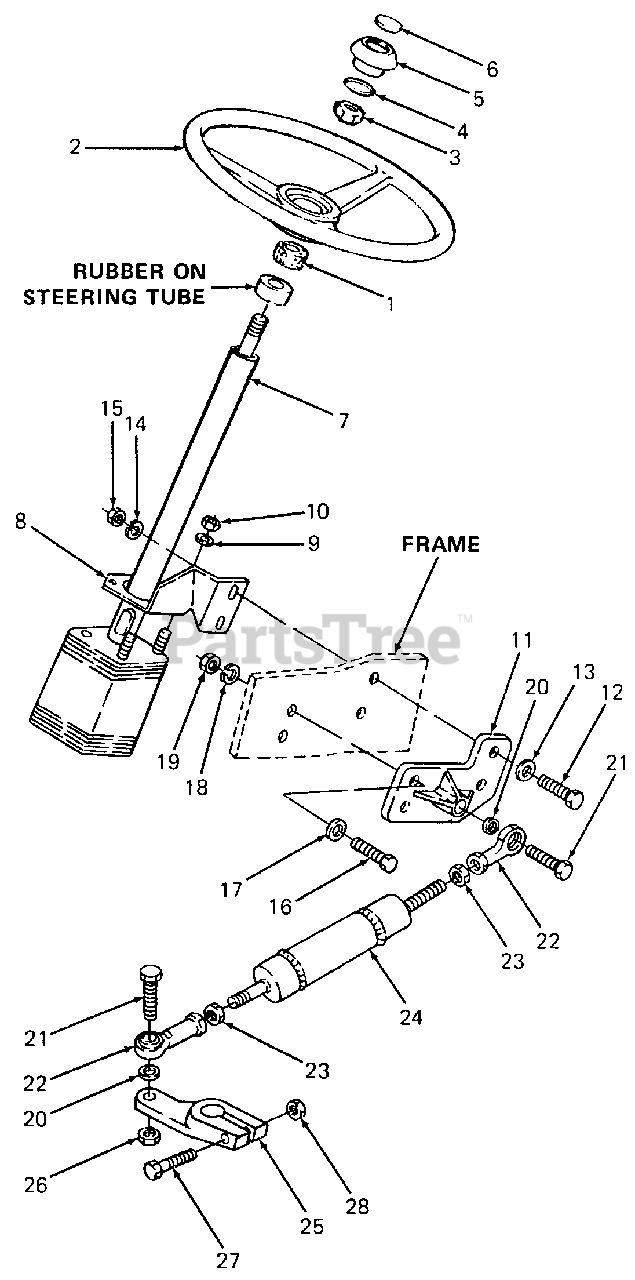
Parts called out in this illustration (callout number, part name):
1	Seal, Steering Gear
2	Wheel, Steering
3	Nut, Hex Jam, 5/8-18
5	Cap, Steering Wheel
6	Label, Steering Cap
7	Steering Column Assy
8	Bracket, Steering Mounting
9	Washer, Bell, .345 X .88 X .060 Thk
10	Nut, Hex, 5/16-24 GR5
13	Washer, Flat, .385 X .87 X .06 Thk HDN
14	Washer, Lock, 3/8
15	Nut, Hex Center Lock, 3/8-16 GR5
16	Screw, Hex Cap, 1/2-13 X 1.25 Lg GR5
17	Washer, Flat, .51 X 1.12 X .06 Thk HDN
18	Washer, Lock, 1/2
19	Nut, Hex Center Lock, 1/2-13 GR5
20	Washer, Flat, .531 X .688 X .054 Thk
21	Screw, Hex Cap, 1/2-20 X 1.5 Lg GR5
22	Alignaball End, 1/2-20
23	Nut, Hex Jam, 1/2-20 GR5
24	Cylinder, Power Steering
25	Arm, Steering
26	Nut, Hex, 1/2-20 GR5
27	Screw, Hex Cap, 5/16-18 X 1.38 Lg GR5
28	Nut, Hex Center Lock, 5/16-18 GR5
